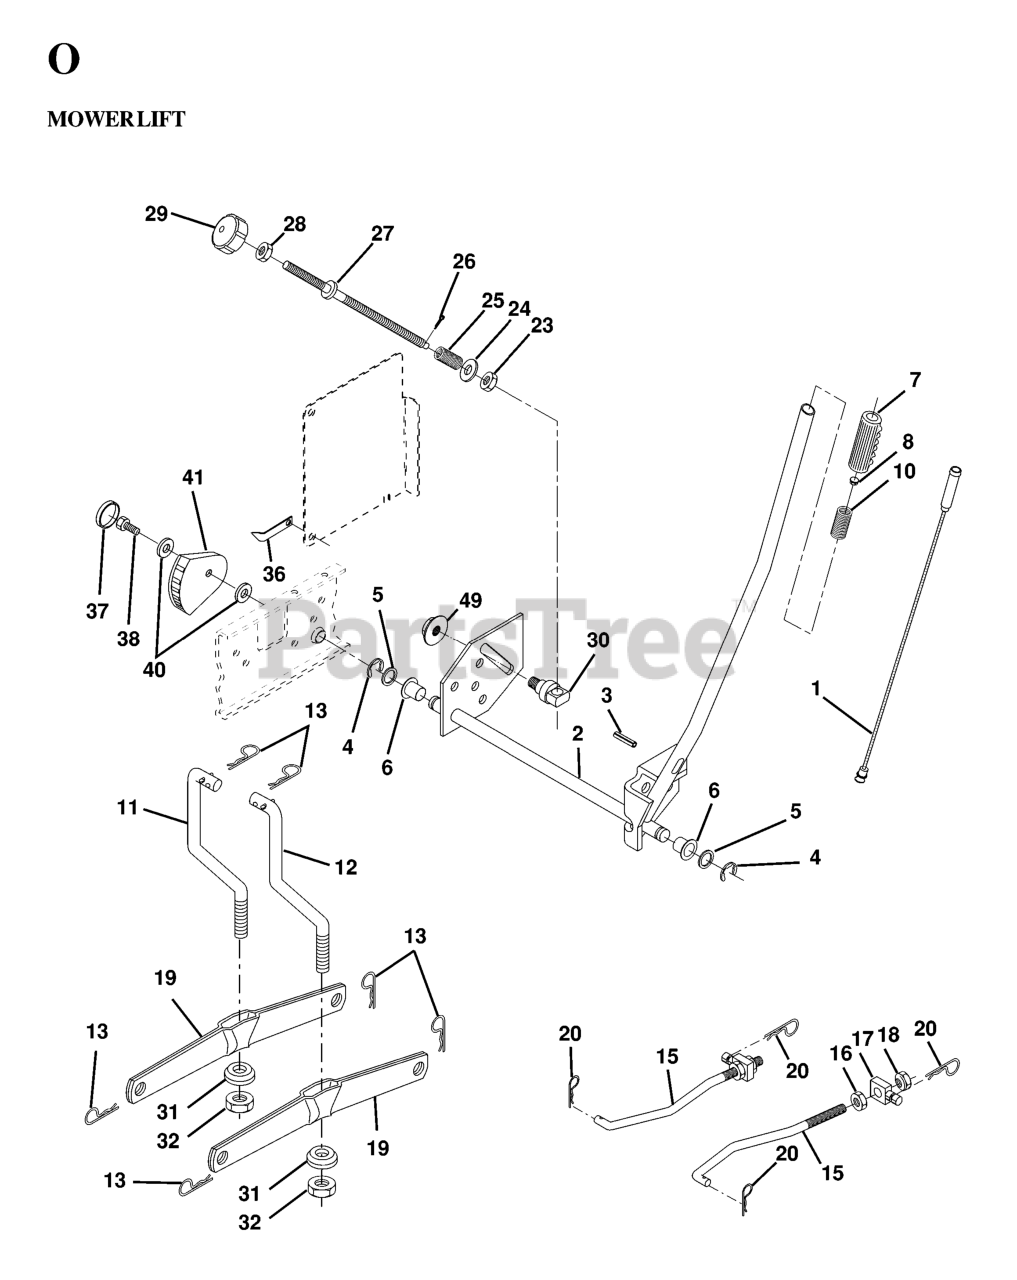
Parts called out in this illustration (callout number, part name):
1	WIRE.INNER.HANDLE.LIFT.LEVER
2	SHAFT ARM LIFT RH
3	PIN GROOVE.
4	RETAINING RING LT
6	BEARING.NYLON
7	GRIP HANDLE
8	PLUNGER BUT KIT
10	SPRING, COMP T
11	LINK LIFT LH
12	LINK LIFT RH
13	RETAINER-SPRNG RB
15	FRONT LINK
16	NUT.HEX.JAM.1/2-13
17	TRUNION
18	NUT.LK.W/WSH.1/2.
19	ARM.REAR.SUSPENSION
20	SPRING RETAINER
25	SPRING**
26	COTTER PIN
27	ROD ADJ LIFT
28	NUT
29	KNOB INF 3/8-16
31	BEARING PIVOT
32	NUT CROWNLOCK 3/8-24
36	POINTER, HEIGHT INDICATOR(2 2)
38	SCREW.THDROL.5/16-18X3/4.TTY
41	IND. HEIGHT STLT
49	NUT
